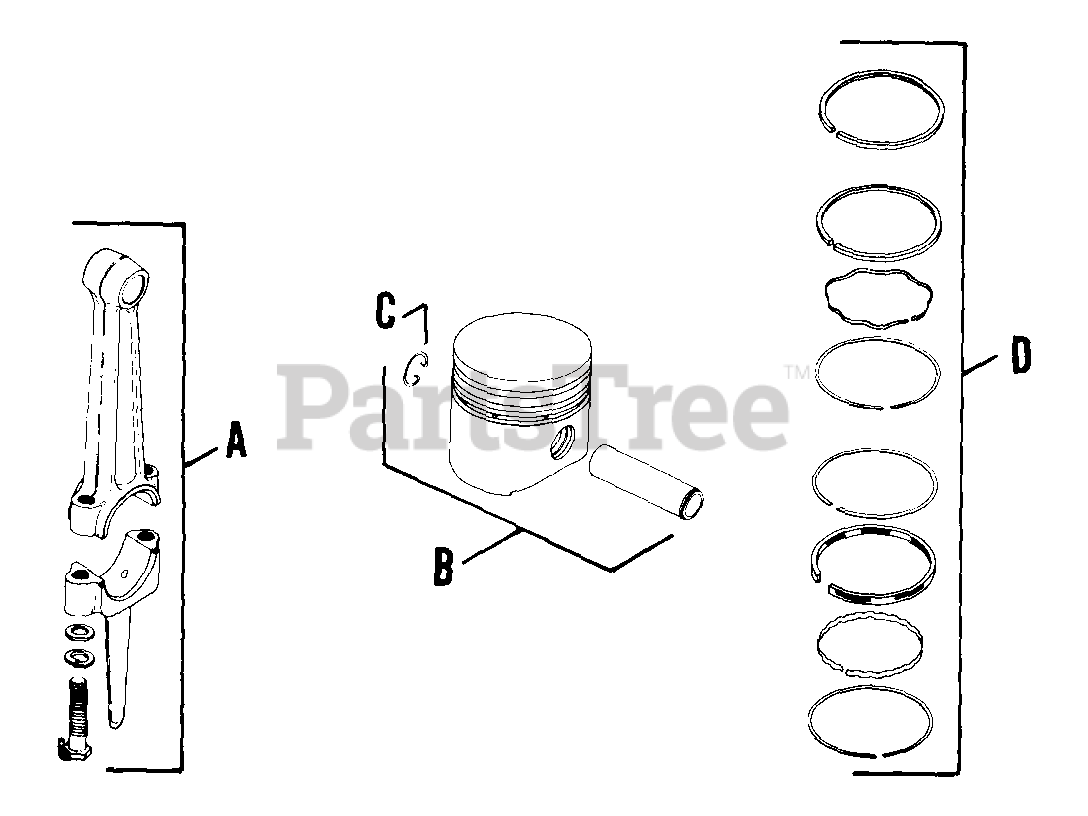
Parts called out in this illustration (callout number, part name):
A	ROD - USE 47 067 03
A	ROD - USE 47 067 04
B	PISTON SET - USE 47 874 01
B	PISTON SET - USE 47 874 02
B	PISTON SET - USE 47 874 03
B	PISTON SET - USE 47 874 04
B	PISTON SET - USE 47 874 05
C	PIN - USE 47 018 01
D	RINGS STD. - DISCONTINUED
D	RINGS .010
D	RINGS .020
D	RINGS .030
